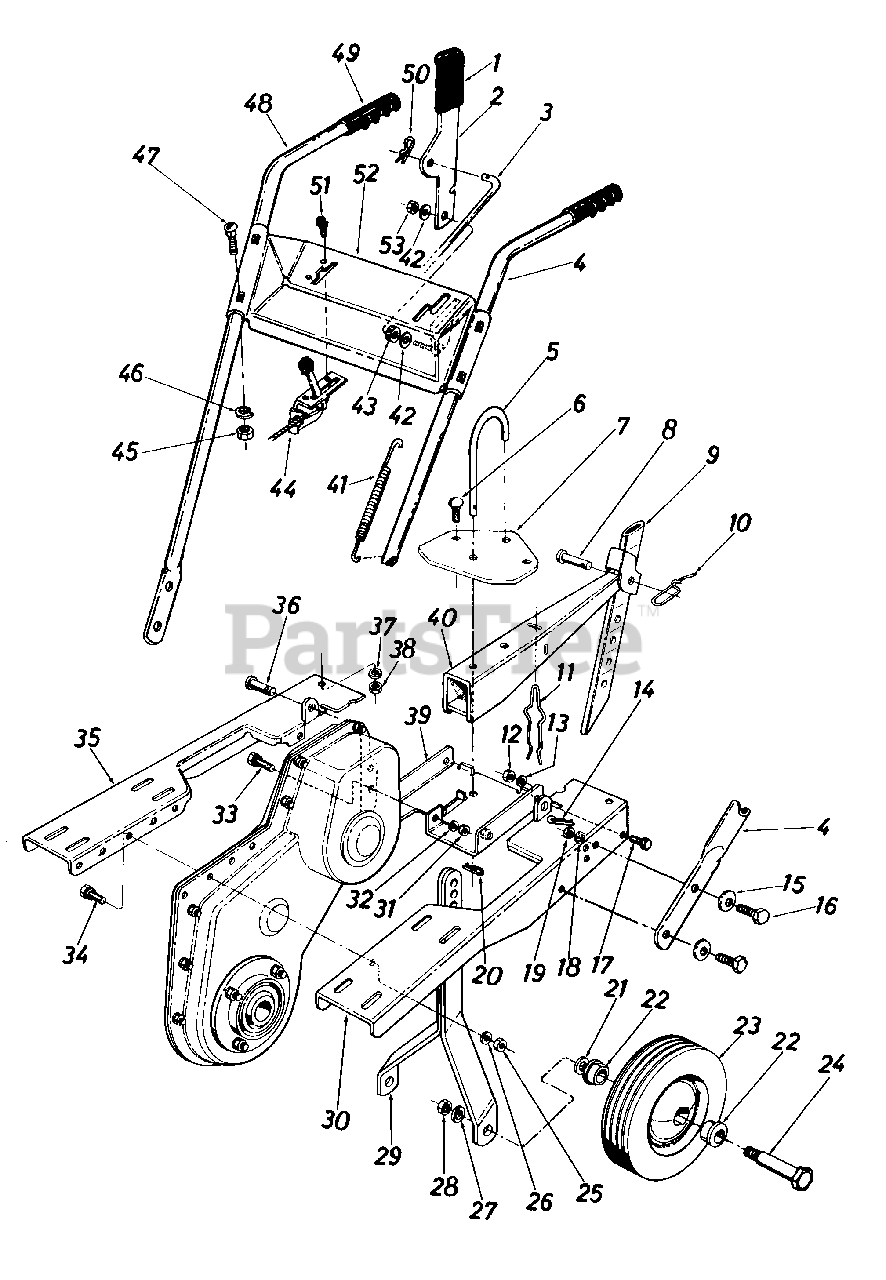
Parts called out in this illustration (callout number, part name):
2	Clutch Lever
3	Clutch Control Rod
4	Handle - L.H.
5	"U"-Clevis Pin .500" Dia.
6	Carriage Bolt 5/16-18 x .75" Lg.
7	"U" Channel Plate
8	Clevis Pin 1/2" Dia.
9	Depth Bar
10	Spring Pin
11	Depth Bar Spring
12	Hex Nut 5/16-18 Thd.
13	L-Wash. 5/16" I.D.
14	Int. Cotter Pin 1/2" Dia.
15	Belleville Wash. 3/8" I.D.
16	Hex Bolt 3/8-16 x 1.00" Lg.
17	Hex Sems Bolt 5/16-18 x .75" Lg.
18	L-Wash. 3/8" I.D.
19	Hex Nut 3/8-16 Thd.
20	Int. Cotter Pin 1/2" Dia.
21	Belleville Wash.
22	Flange Bearing
23	Wheel Ass'y. Comp. 10 x 2.75
24	Shoulder Bolt .625" Dia. x 2.75" Lg. (1/2-20 Thd.)
25	Hex Nut 5/16-18 Thd.
26	L-Wash. 5/16" I.D.
27	L-Wash. 1/2" I.D.
28	Hex Cent. L-Nut 1/2-20 Thd.
29	Wheel Bracket Ass'y.
30	Engine "U"-Channel Ass'y. - L.H.
31	Hex Nut 5/16-18 Thd.
32	L-Wash. 5/16" I.D.
33	Hex Sems Bolt 5/16-18 x 1.00" Lg.
34	Hex Sems Bolt 5/16-18 x 1.00" Lg.
35	Engine "U"-Channel Ass'y. - R.H.
36	Clevis Pin
37	L-Wash. 5/16" I.D.
38	Hex Nut 5/16-18 Thd.
39	"U"-Channel Bracket Ass'y.
40	Tailpiece Assembly
41	Extension Spring
42	Fl-Wash. .380" I.D.
43	Rubber Washer
44	Throttle Control Ass'y. Comp.
45	Hex Nut 5/16-18 Thd.
46	L-Wash. 5/16" I.D.
47	Carriage Bolt 5/16-18 x .75" Lg.
48	Handle - R.H.
49	Grip - Handle
50	Int. Cotter Pin 1/2" Dia.
51	Hex Wash. Hd. AB-Tap Scr. #8 x .62" Lg.
52	Handle Panel
53	Hex Inst. L-Nut 3/8-24 Thd.
